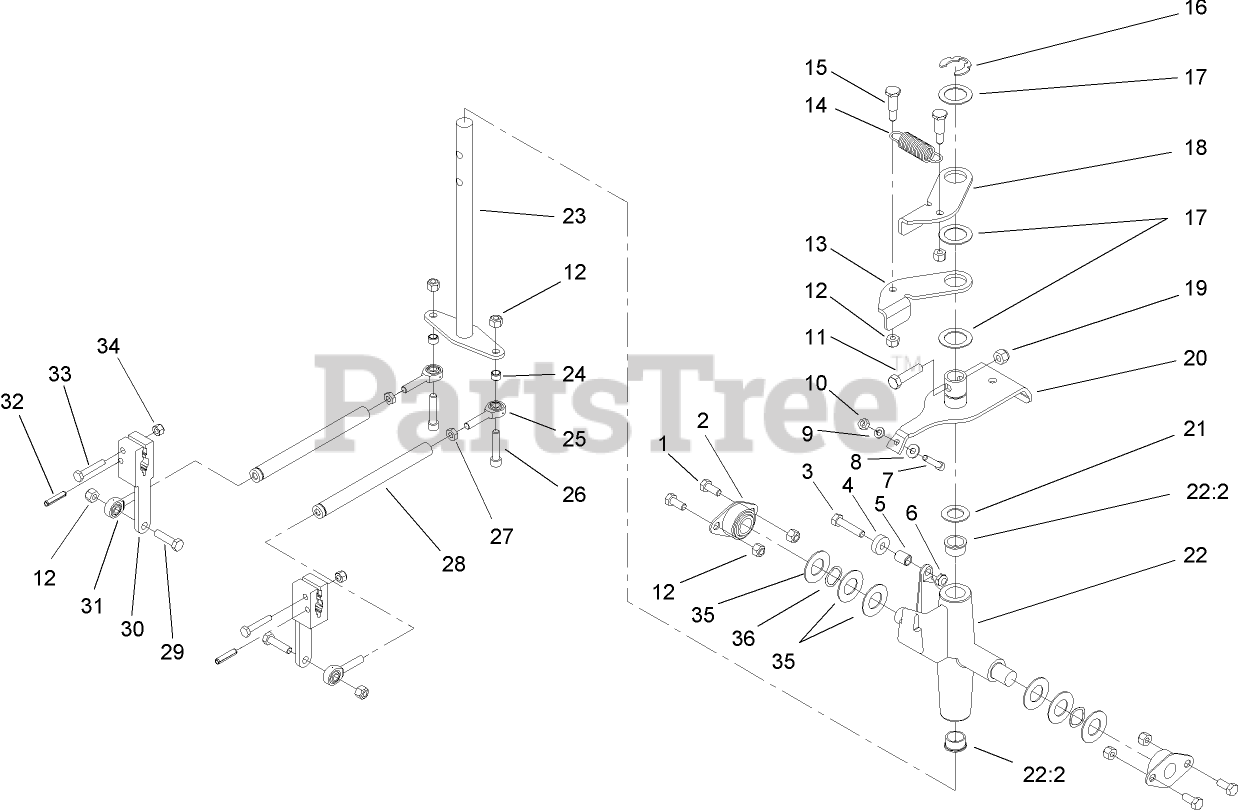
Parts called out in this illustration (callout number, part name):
1	SCREW-HH
2	BUSHING
3	SCREW-HH
4	BEARING-BALL
5	SPACER-LEVER, CONTROL
6	NUT-LOCK, NI
7	SCREW-HSH
8	WASHER-FLAT
9	WASHER-LOCK
10	NUT-HEX
11	SCREW-HH
12	NUT-LOCK, NI
13	LEVER-RETURN, RH
14	SPRING-EXTENSION
15	SCREW-SHOULDER
16	RING-RETAINING
17	WASHER-PLAIN
18	LEVER-RETURN, LH
19	NUT-LOCK, NI
20	PIVOT LEVER ASM
21	WASHER-THRUST
22	CONTROL SUPPORT ASM
22:2	BEARING-FLANGE
23	DRIVE ROD ASM
24	SPACER-LEVER, TRACTION
25	BEARING-ROD END, RH
26	SCREW-HSH
27	NUT-JAM
28	ROD-LINKAGE
29	SCREW-HH
30	ARM-CONTROL, PUMP
31	BEARING-ROD END, LH
32	PIN-SPRING, SLOTTED
33	SCREW-HH
34	NUT-LOCK, NI
35	WASHER-FLAT
36	WASHER-SPRING, WAVE
